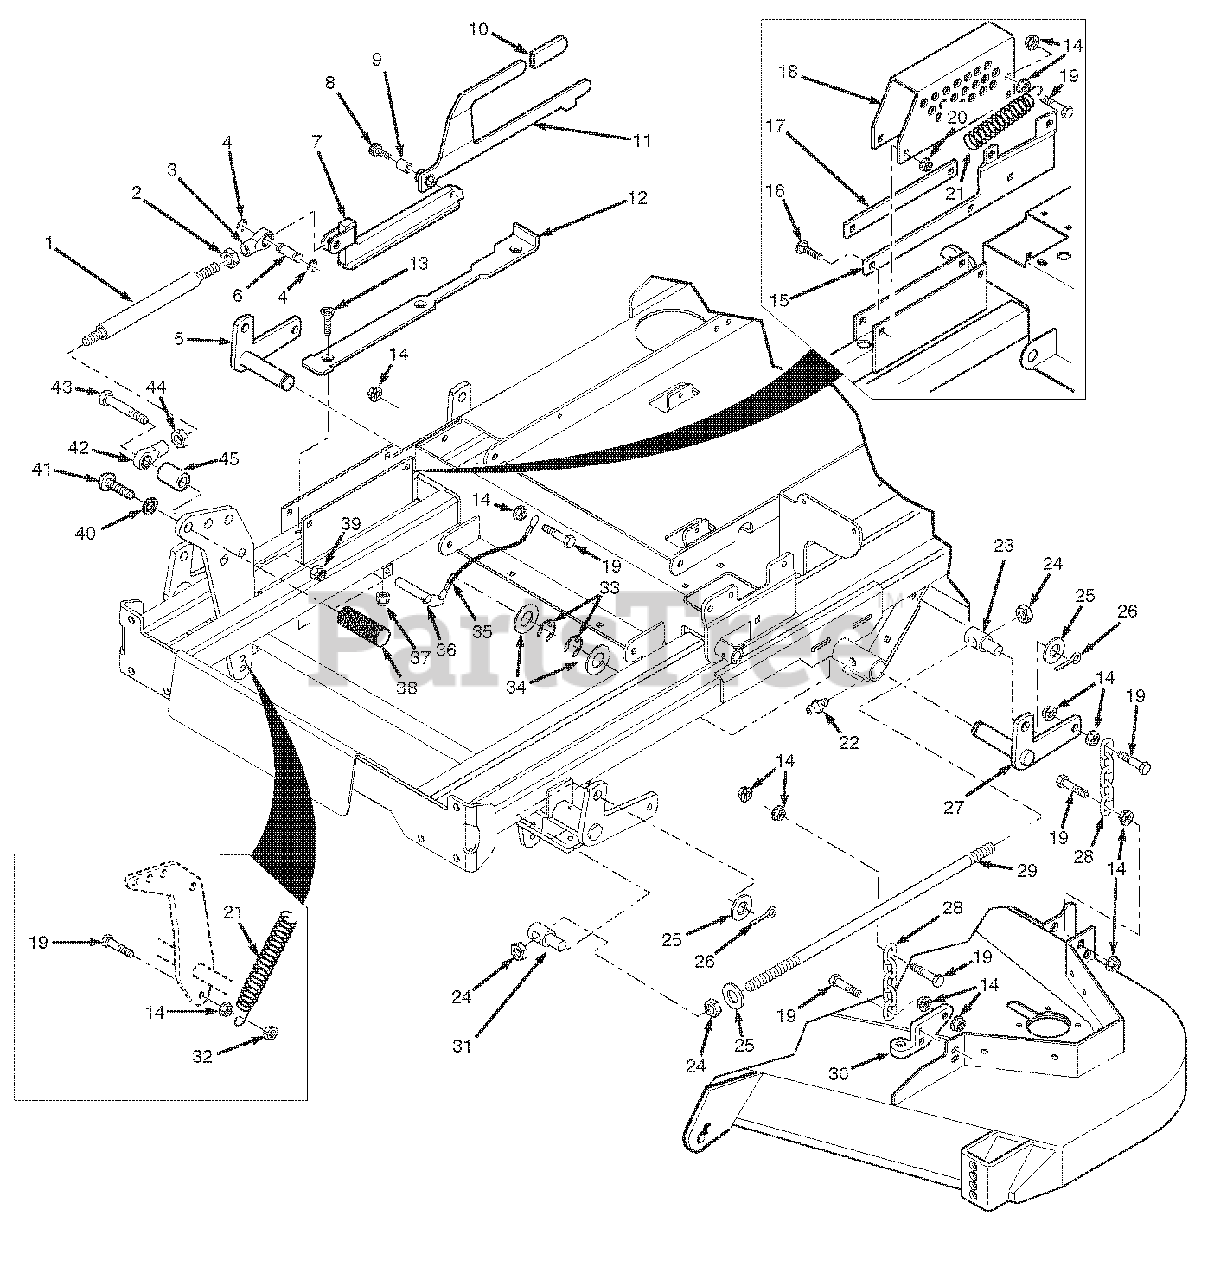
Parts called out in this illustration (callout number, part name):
1	Link, Deck Lift
2	Nut, Jam 1/2-20 LH
3	Rod End, Female - 1/2-20 LH
4	Ring, Retaining 1/2" External "E"
5	Bellcrank Weldment, RH Rear
6	Pin, Decklift
7	Slide Weldment, Height Adjustment
8	Bolt, Shoulder 1/2 x 3/4"
9	Bushing, .502 ID.
10	Grip, Deck Latch
11	Deck Latch
12	Lockplate, Decklift
13	Screw, Cap 5/16-18 x 3" FHHS
14	Nut, Hex Serrated Flange 3/8-16
15	Guide, Long
16	Bolt, Carriage 5/16-18 x 1"
17	Guide, Short
18	Bracket, Cutting Height Adjustment
19	Bolt, Hex Head 3/8-16 x 1-1/2"
20	Nut, Hex Serrated Flange 5/16-18
21	Spring, Helper
22	Grease Fitting
23	Swivel Joint, LH
24	Nut, Hex 5/8-11
25	Flatwasher, 5/8" (.656 x 1.312 x .095)
26	Cotter Pin, 3/16 x 1"
27	Bellcrank Weldment, LH Rear
28	Chain
29	Stud, 5/8-11 x 26.0"
30	Lever Assembly, Deck Level
31	Swivel Joint, RH
32	Locknut, 3/8-16 Center Lock
33	Ring, Retaining 1" External "E"
34	Flatwasher, 1" (1.062 x 1.50 x .048)
35	Lanyard, Deck Height Pin
36	Ring Pin, 1/2 x 3.06"
37	Nut, 3/8-16 Elastic Stop
38	Foot Pedal, Height Adjustment
39	Nut, Hex Elastic Stop 1/2-13
40	Lockwasher, 5/8"
41	Capscrew, 5/8-11 x 1-1/2"
42	Rod End, Female - 1/2-20 RH
43	Bolt, Hex Head 1/2-13 x 3"
44	Nut, Jam 1/2-20 RH
45	Spacer, Decklift Pedal
